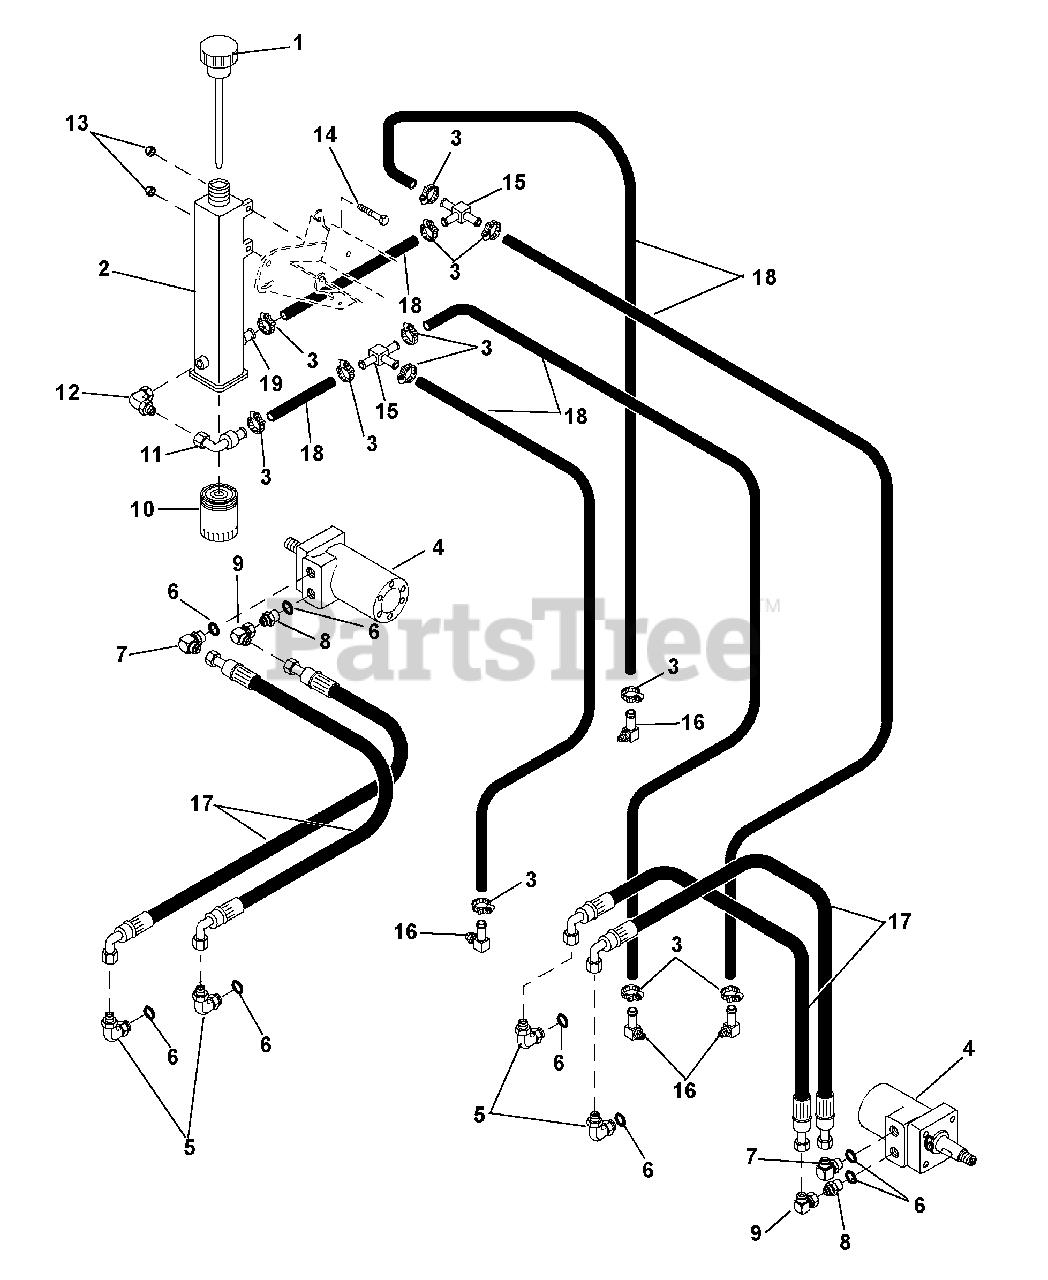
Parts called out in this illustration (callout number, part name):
1	CAP
2	HYDRAULIC RESERVOIR, INC DECAL
3	HOSE CLAMP
4	MOTOR, HYD WHEEL
5	FITTING, INCLUDES O-RING
6	O-RING, INCLUDED WITH FITTING
7	ADAPTER, 8MJ-10MB90
8	ADAPTER, HYD ST 7/8 "O" TO 3/4
9	ADAPTER, 3/4 FESW X 3/4MJICX90
10	ELEMENT, OIL FILTER
11	ELBOW FITTING
12	ADPT 2503-6-6
13	@NUT-LK-NYL .38-16 YWZC
14	BOLT, 3/8-16X.750 HEX 5 Y
15	TEE FITTING
16	FTG-ADPTR .562-18 ST THD
17	HOSE, HIGH PRESSURE
18	HOSE, 3/8 SAE30R7 FUEL & OIL
19	ADAPTER, STRAIGHT FITTING
